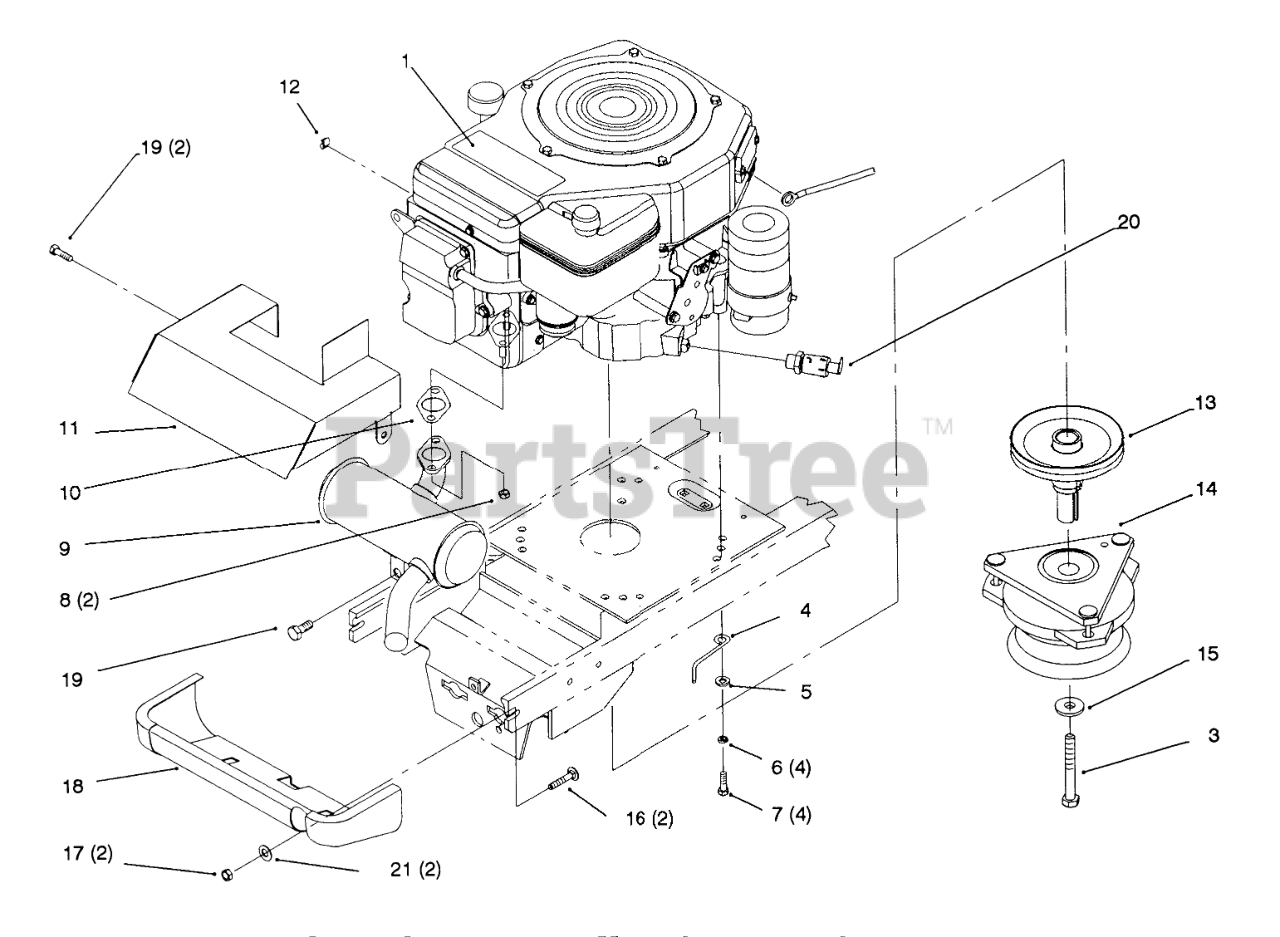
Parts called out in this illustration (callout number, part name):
1	Decal-Toro Power Plus 14 (Only On: 72042,72043,72062,72063)
3	Screw-HH (Only On: 72042,72043,72062,72063)
4	Guide-Belt (Only On: 72042,72062)
5	Washer-Flat (Only On: 72042,72062)
6	Washer-Lock (Only On: 72042,72043,72062,72063)
7	Screw-HH (Only On: 72042,72043,72062,72063)
8	Nut-HHF (Only On: 72042,72043,72062,72063)
9	Muffler (Only On: 72042,72043,72062,72063)
10	Gasket-Exhaust (Only On: 72042,72043,72062,72063)
11	Baffle-Muffler (Only On: 72042,72043,72062,72063)
12	Clip-Wire Retainer (Only On: 72042,72043,72062,72063)
13	Pulley (Only On: 72043,72063)
13	Pulley-Engine (Only On: 72042,72062)
14	Clutch-PTO (Only On: 72042,72043,72062,72063)
15	Washer-PTO (Only On: 72042,72043,72062,72063)
16	Bolt-CARR (Only On: 72042,72043,72062,72063)
17	Nut-Lock (Only On: 72042,72043,72062,72063)
18	Shield-Muffler (Only On: 72042,72043,72062,72063)
19	Screw-HWHTF (Only On: 72042,72043,72062,72063)
20	Valve-Oil Drain (Only On: 72042,72043,72062,72063)
21	Washer-Flat (Only On: 72042,72043,72062,72063)
